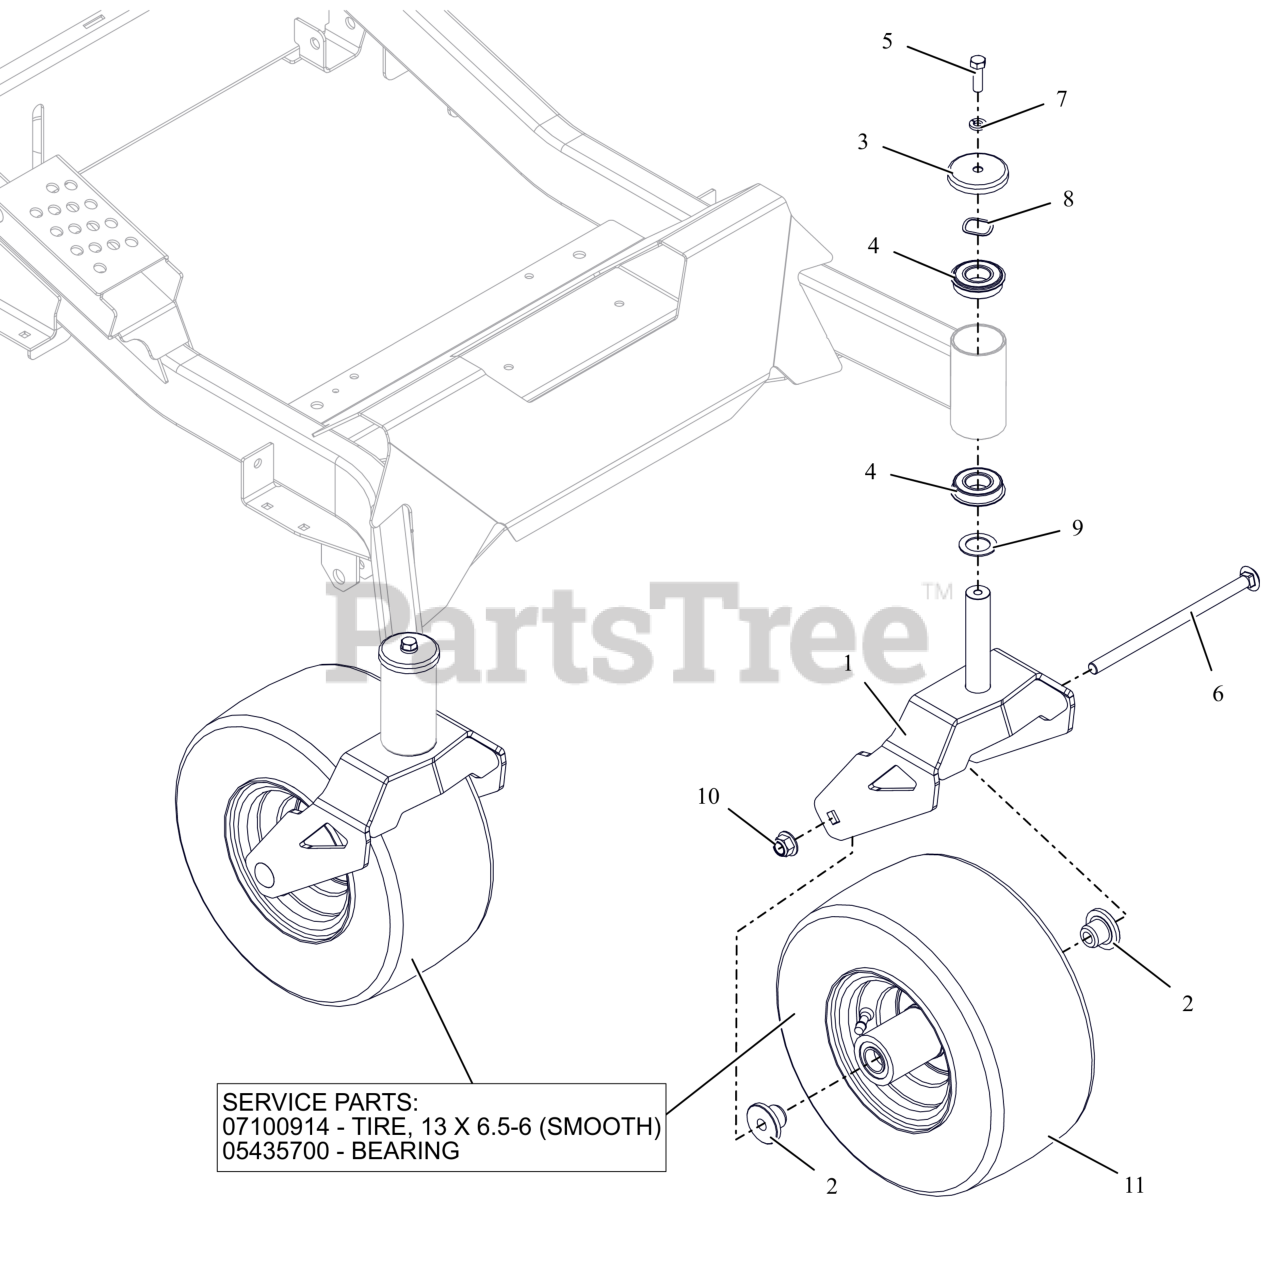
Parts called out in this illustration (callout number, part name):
1	WLDMT, CASTER FORK-HD (ORANGE)
2	SPACER, FRONT WHEEL
3	SHIELD, AXLE BEARING
4	BEARING, BALL -2.000 OD X 1.000 ID X .5625 W/RING
5	BLT, HEX .38-16X1.25 G5 ZCC
6	BLT, RHSN .50-13X9.00 G5 ZCC
7	WSHR, LK-HVY .375X.115 ZCC
8	WSHR-WAVE 1.0X1.25X.028 .145FH
9	WSHR-HRD-THRS 1.007X1.542X.062
10	NUT,NYL-FLG .50-13 GF ZCC
11	ASM, WHL/TIRE 13X6.50-6
11	LAWN TIRE FRONT, 13X6.50-6 SMOOTH
11	BRG, 25MM ID X 52MM OD X 15MM
11	VALVE STEM ASS'Y
11	TIRE TUBE, 13/6.5-6 4 PLY TR87 90 BENT VALVE
